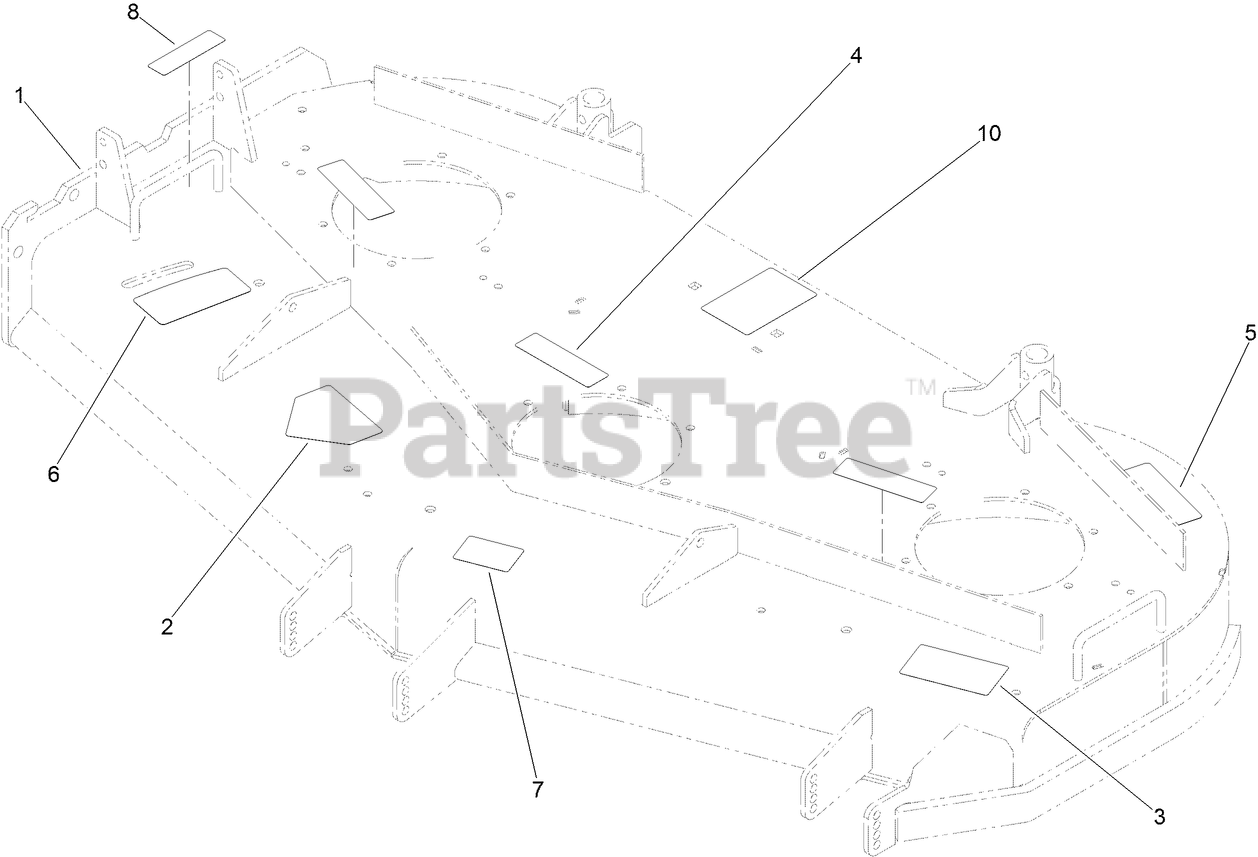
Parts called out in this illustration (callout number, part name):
1	52 INCH DECK ASM
2	DECAL-DANGER
3	DECAL-DANGER
4	DECAL-MISSING, COVER
5	DECAL-TORQUE, BLADE BOLT
6	DECAL-ADJUSTMENT, BAFFLE
7	DECAL-SCALP, ANTI
8	DECAL-WARNING, DEFLECTOR
10	DECAL-ROUTING, BELT
